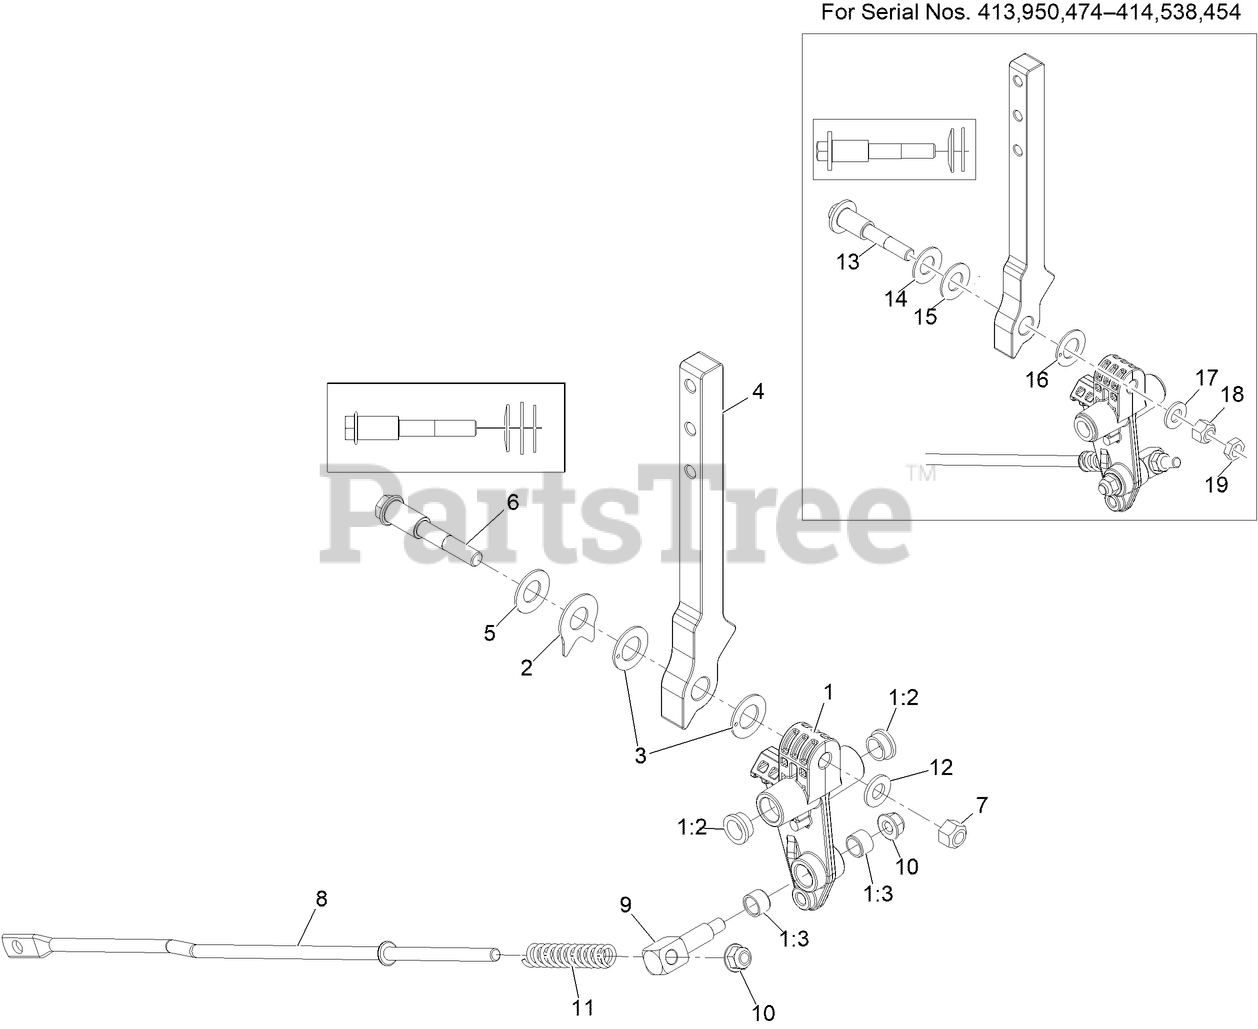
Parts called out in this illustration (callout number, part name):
1	CONTROL ARM ASM
1:2	BUSHING
1:3	BUSHING-SLEEVE
2	Spacer, Anti-Rotation
3	WASHER-FRICTION
4	Lever, Motion Control
5	WASHER-BELLEVILLE
6	Bolt-Pivot
7	NUT-LOCK, CONE
8	LINK-CONTROL
10	NUT-HF, NI
11	SPRING-RETURN, NEUTRAL
12	WASHER-FLAT
13	BOLT-PIVOT
14	WASHER-BELLEVILLE
16	WASHER-FRICTION
17	WASHER-FLAT
18	NUT-LOCK, CONE
19	NUT-JAM
